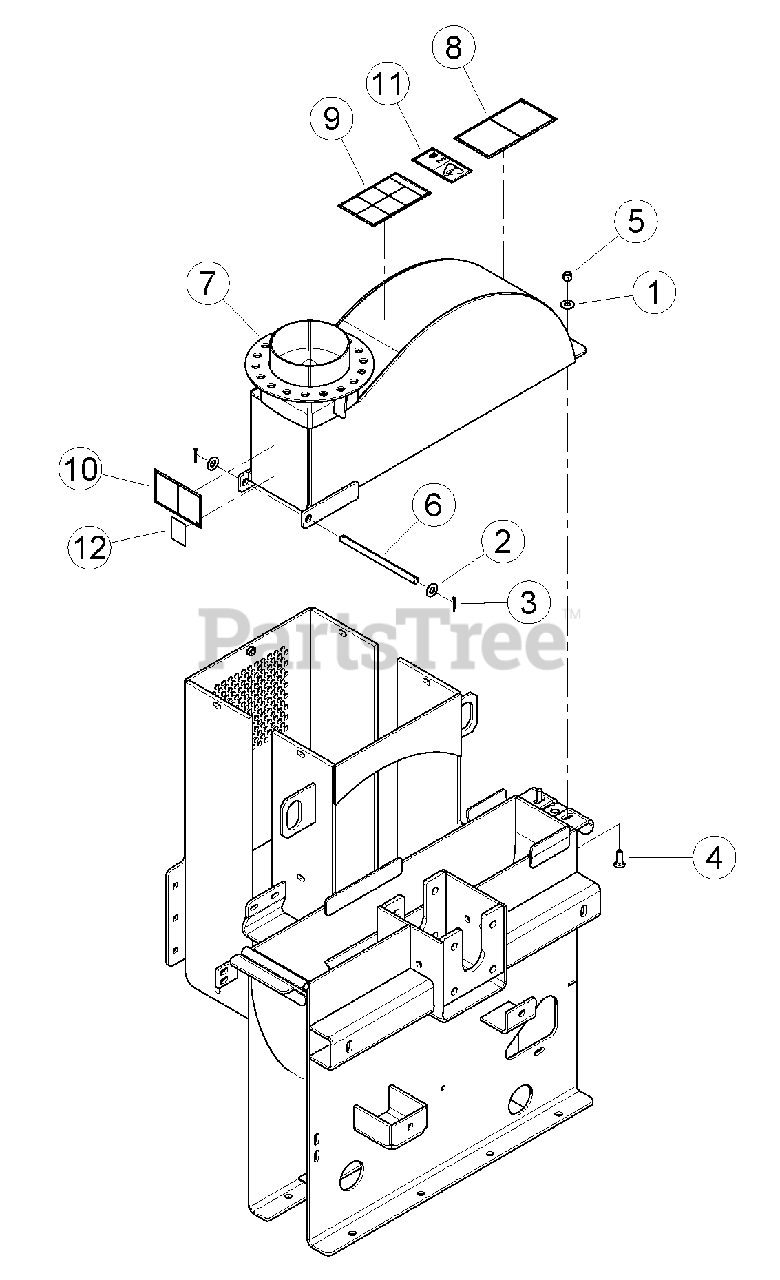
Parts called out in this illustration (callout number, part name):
1	WASHER, 3/8 FLAT ZP
2	WASHER, 1/2 SAE FLAT ZP
3	PIN, 1/8 X 1.00 COTTER ZP
4	BOLT, 3/8 X 1-1/4 CRG GR5 NC ZP
5	NUT, 3/8 NE NYLOCK ZP
6	SHAFT CHIPPER TOP PIVOT
7	ASSEMBLY, CHIPPER HOUSING TOP
8	DECAL, KNIFE ACCESS ISO
9	DECAL, OPERATING INSTRUCTIONS ISO
10	DECAL, DISCHARGE ISO
11	DECAL, MAINTENANCE ISO
12	DECAL, ECHO BEARCAT QR CODE
